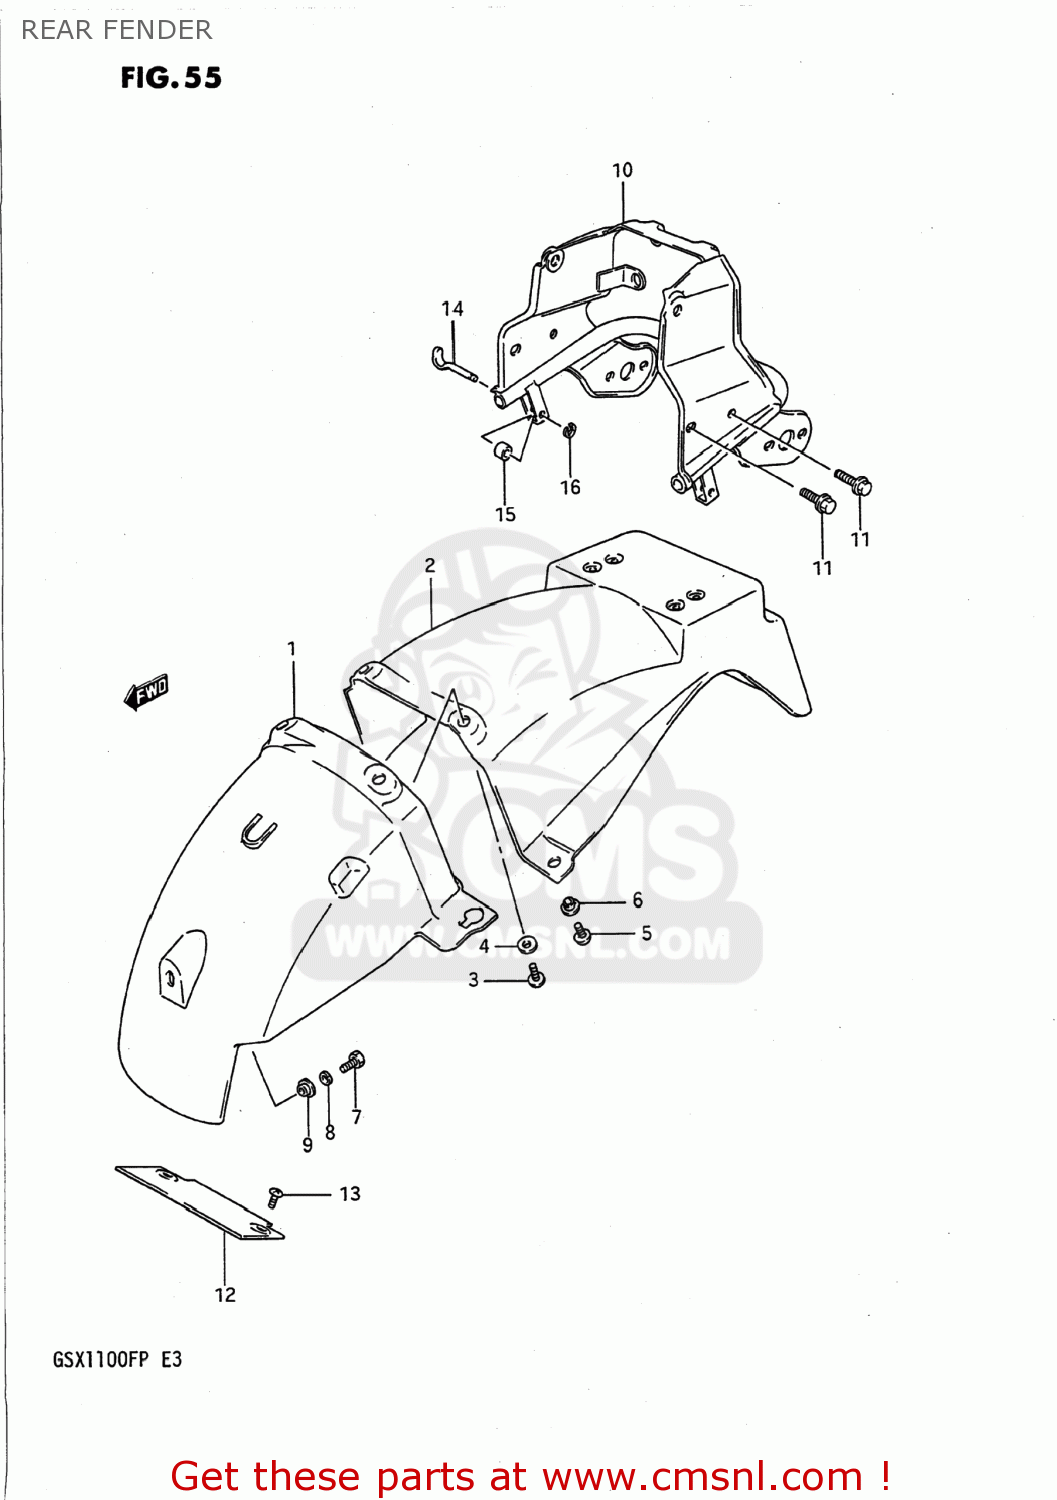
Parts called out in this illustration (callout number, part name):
1	BODY,REAR FENDER,FRONT
2	BODY,REAR FENDER,REAR
3	SCREW
4	WASHER
5	SCREW
6	WASHER
7	BOLT
8	WASHER,LOCK
9	WASHER
10	REINF,RR FENDER
11	BOLT
12	GUARD,REAR FENDER,FRONT
13	SCREW
14	ROD,GRIP
15	SPACER,GRIP ROD
16	E RING
